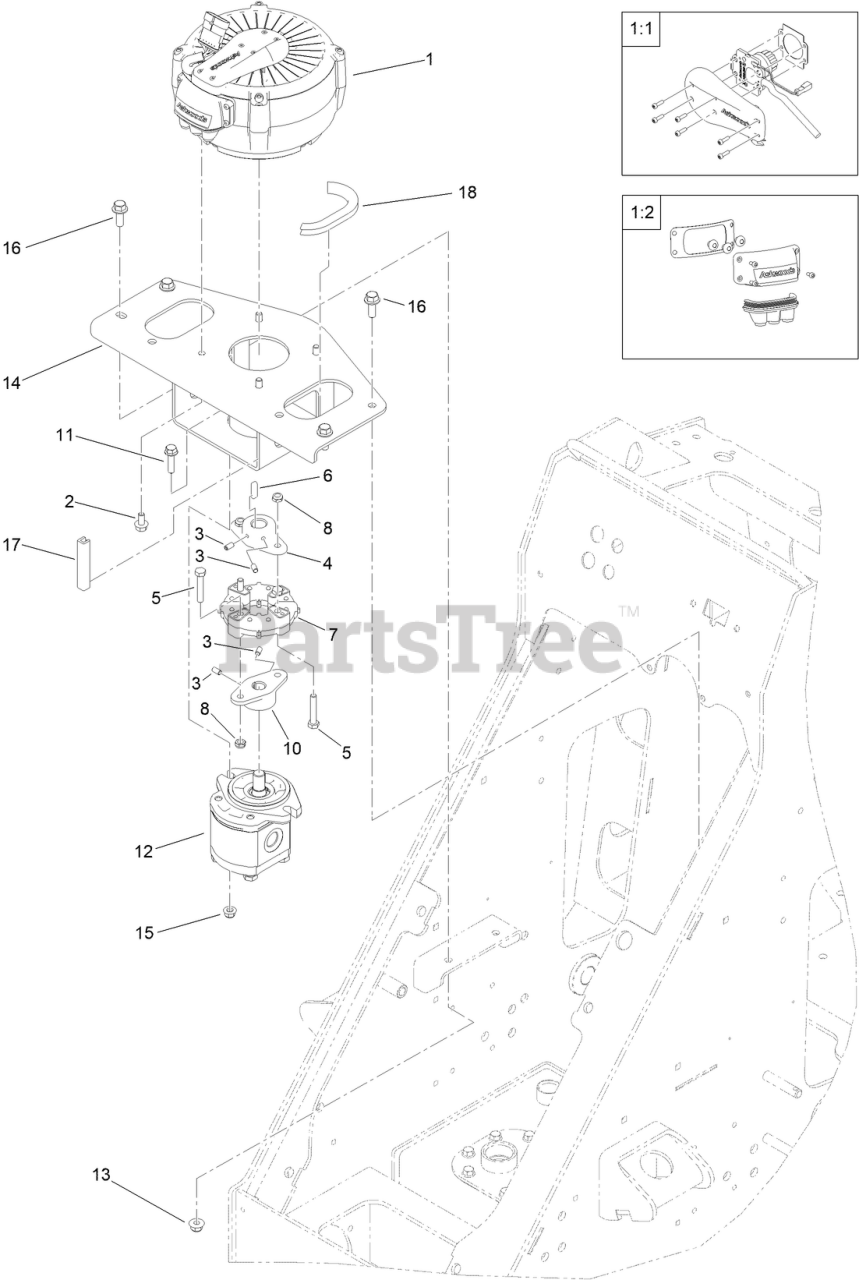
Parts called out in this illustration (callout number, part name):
1	MOTOR/GEN
1:1	KIT-ENCODER, MTR/GEN
1:2	KIT-TERMINAL COVER
2	SCREW-HHF
3	SCREW-SET, HSH
4	HUB-PUMP
5	SCREW-HH
6	KEY-SQUARE
7	COUPLER-RUBBER
8	NUT-LOCK, NI
10	HUB-PUMP
11	SCREW-HHF
12	PUMP-HYDRAULIC
13	NUT-HF, NI
14	PLATE-MOTOR ASM [RED]
15	NUT-HF, NI
16	SCREW-HHF
18	TRIM-SEAL
